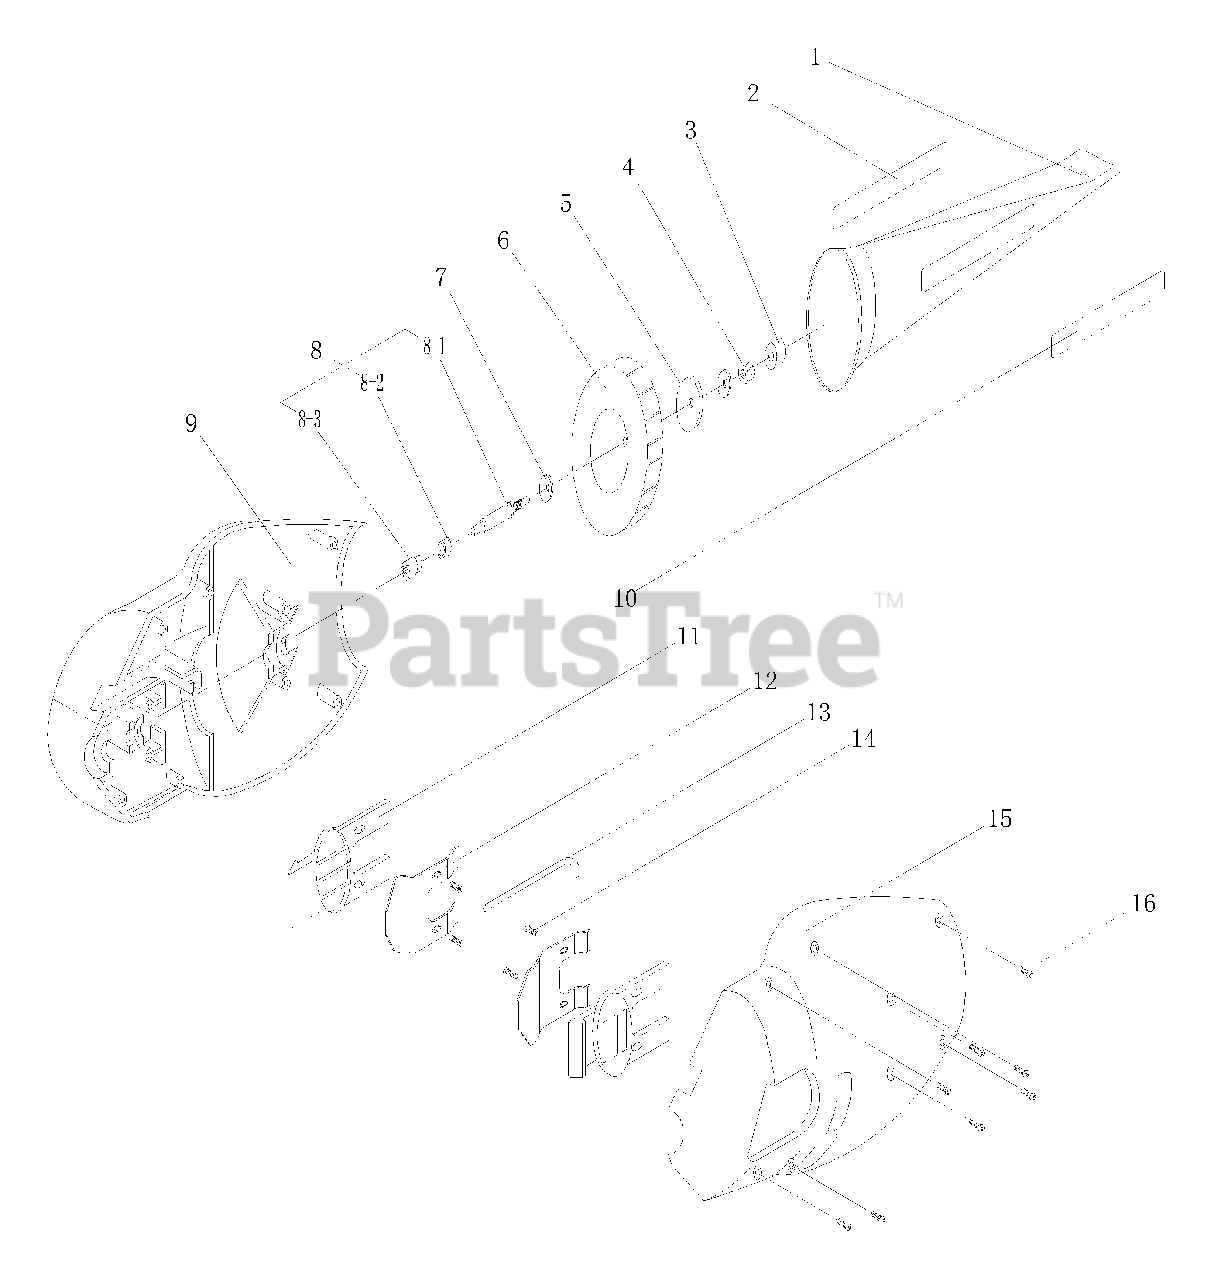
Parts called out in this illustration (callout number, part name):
8	PIVOT ASS'Y
9	CONNECT (L)
12	SPRING LAMINATION
15	CONNECT (R)
